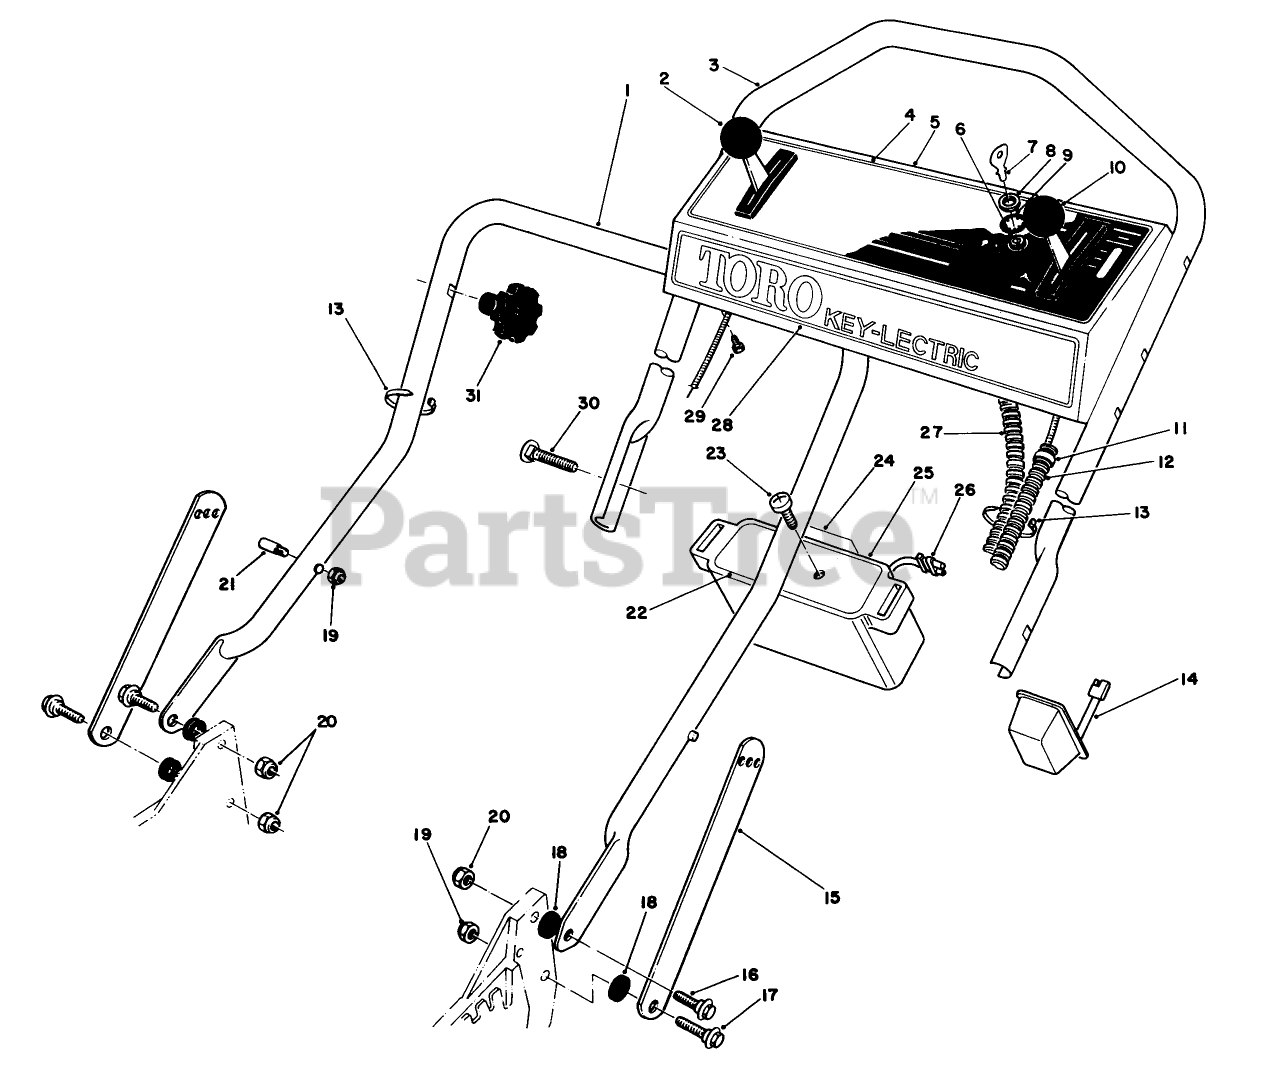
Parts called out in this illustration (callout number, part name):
2	GROUND SPEED CONTROL
6	STARTER SWITCH ASM
8	NUT-HH
9	WASHER-LOCK
10	SERVICE THROTTLE CONTRO
11	FITTING-RING
13	TIE-CABLE
16	SCREW-SHOULDER
17	SCREW-SHOULDER
18	SPACER
19	NUT-LOCK, NI
20	NUT-LOCK, NI
21	HANDLE PIN
27	WIRE HARNESS
29	SCREW-HWHTF
